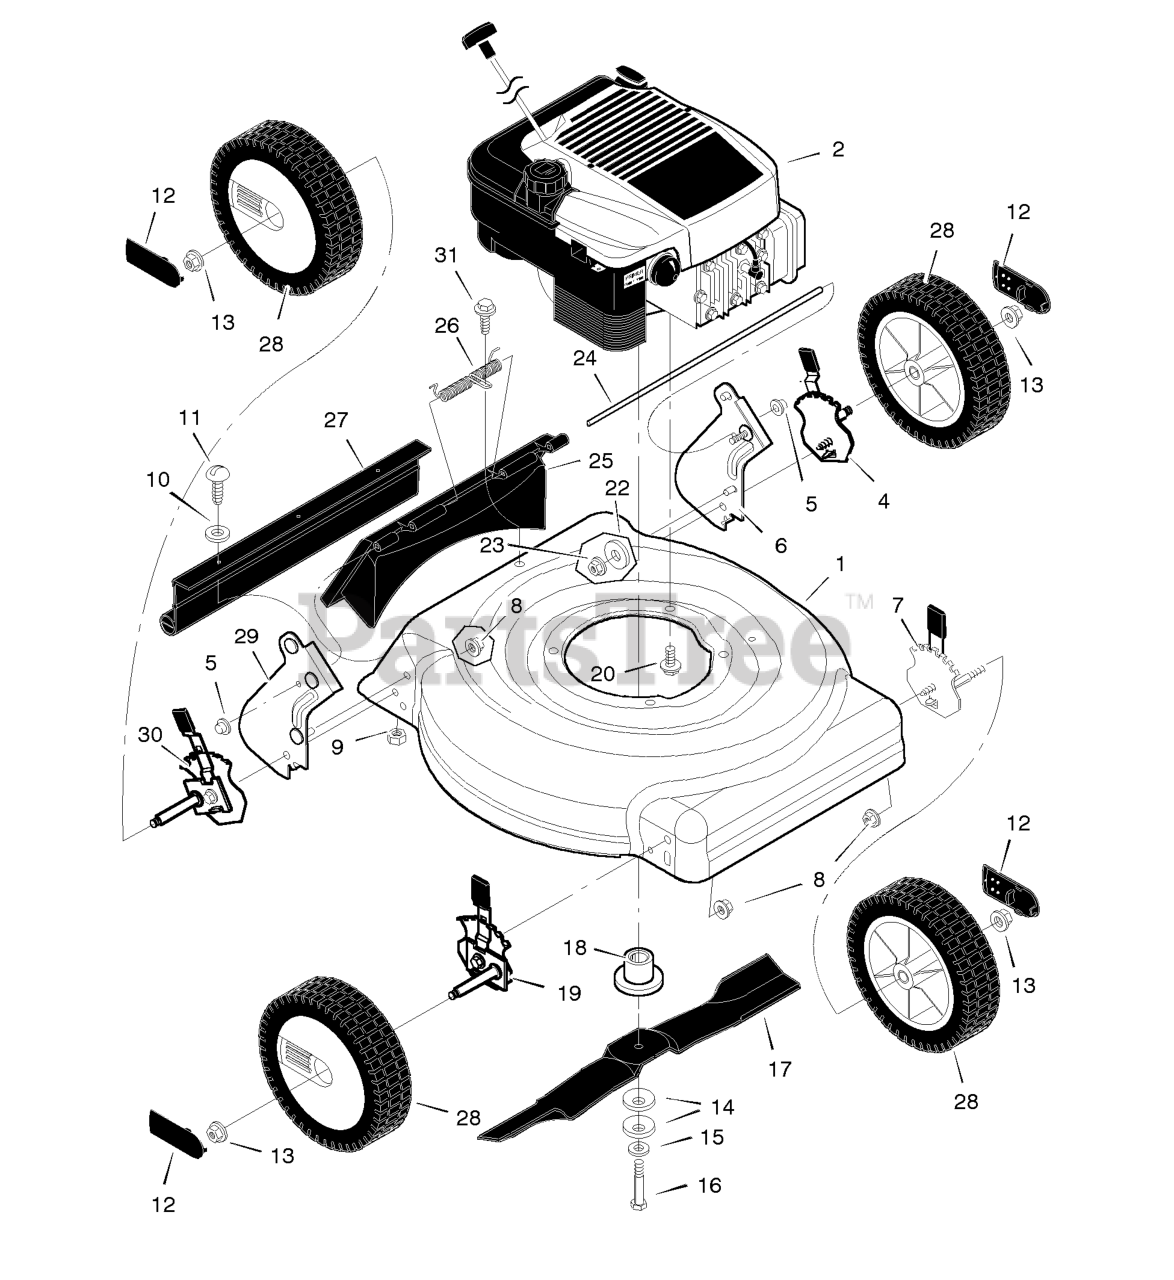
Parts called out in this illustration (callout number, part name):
1	Housing
2	Engine
4	Adjuster, Left Rear Height
5	Push On Cap
6	Bracket, Left Handle
7	Adjuster, Left Front Height
8	Nut, Flange
9	Nut, Hex
12	Hub Cap
13	Nut, Flange
14	Washer, Belleville
18	Adapter, Blade
19	Adjuster, Right Front Height
20	Bolt, Engine
22	Washer
23	Nut, Flange
24	Rod, Pivot
25	Door, Rear
27	Guard, Rear
29	Bracket, Right Handle
30	Adjuster, Right Rear Height
